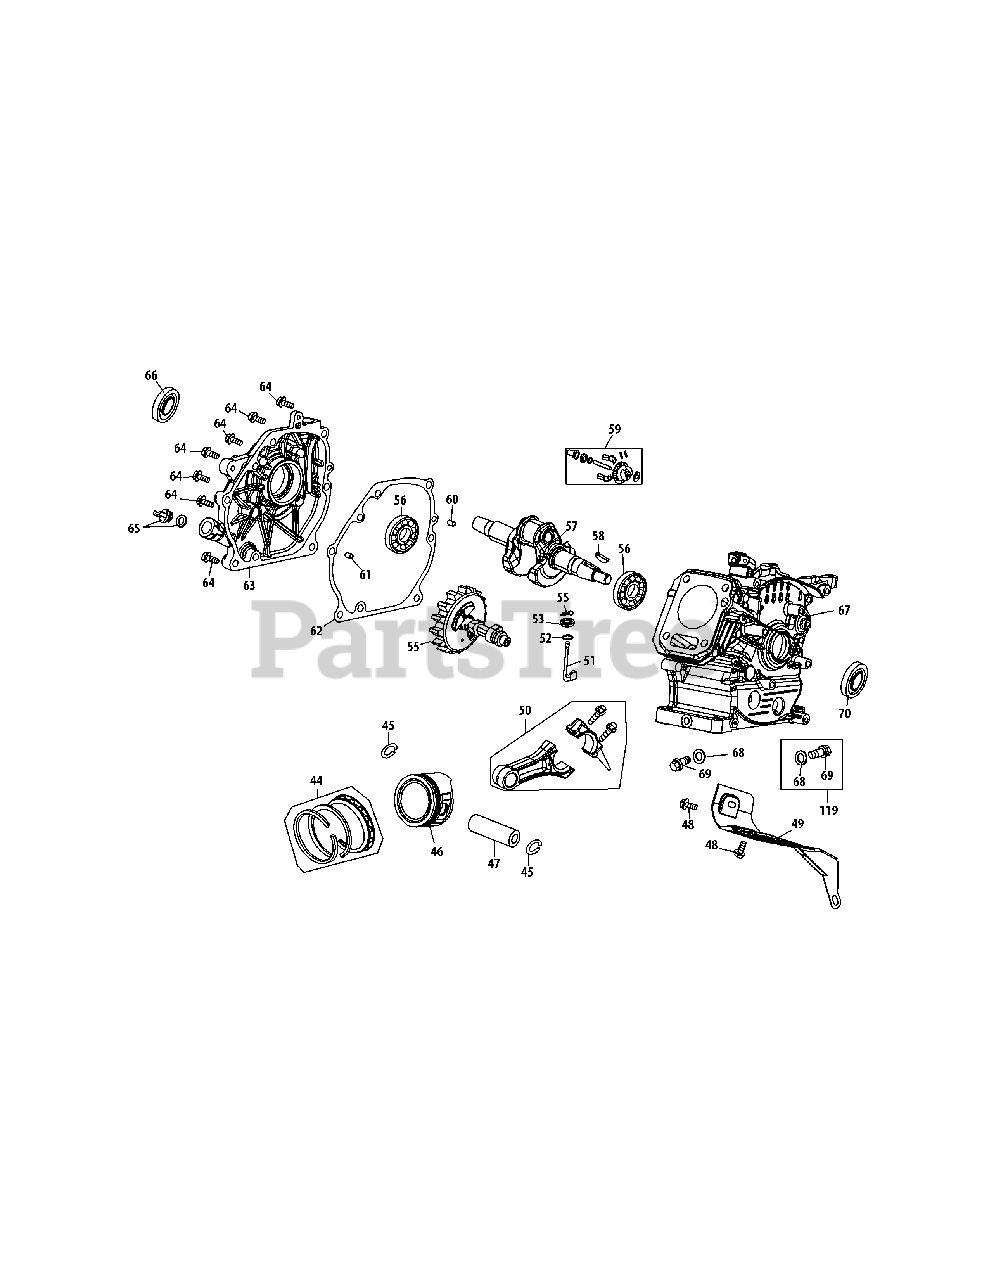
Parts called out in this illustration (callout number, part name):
44	Piston Ring Set
45	Piston Pin Snap Ring
46	Piston
47	Piston Pin
48	Bolt M6×12
49	Air Shield
50	Connecting Rod Assembly
51	Governor Arm Shaft
52	Washer 5.2×1.9
53	Governor Seal
54	Cotter Pin
55	Camshaft Assy.
56	Radial Ball Bearing,6205
57	Crankshaft Assembly
58	Woodruff Key
59	Governor Gear/Shaft Asm
60	Dowel Pin 7×14
61	Dowel Pin 9×14
62	Crankcase Cover Gasket
63	Cover Comp,Left Crankcase
64	Bolt M8×32
65	Dipstick Assembly
66	Oil Seal,25×41.25×6
67	Short Block
68	Washer 10×16×1.5
69	Oil Drain Plug
70	Oil Seal 25×41.25×6
119	Oil Drain Plug & Washer Assembly
